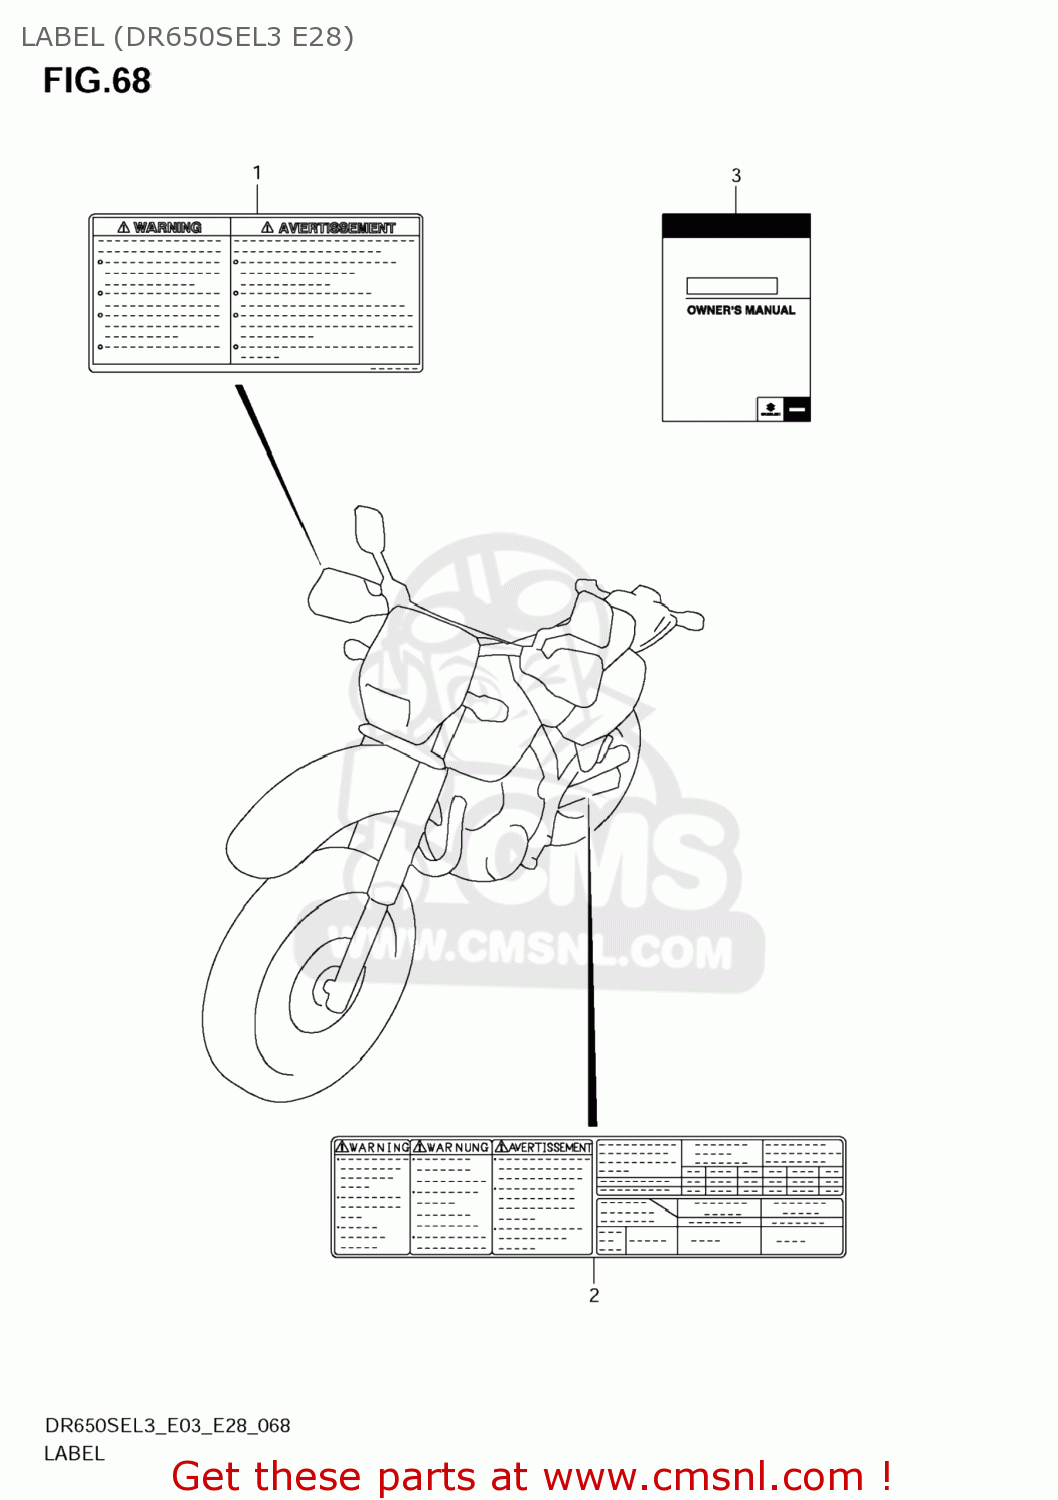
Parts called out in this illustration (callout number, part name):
1	LABEL,GENERAL WARNING
2	LABEL,TIRE INFORMATION
3	MANUAL,OWNER'S
